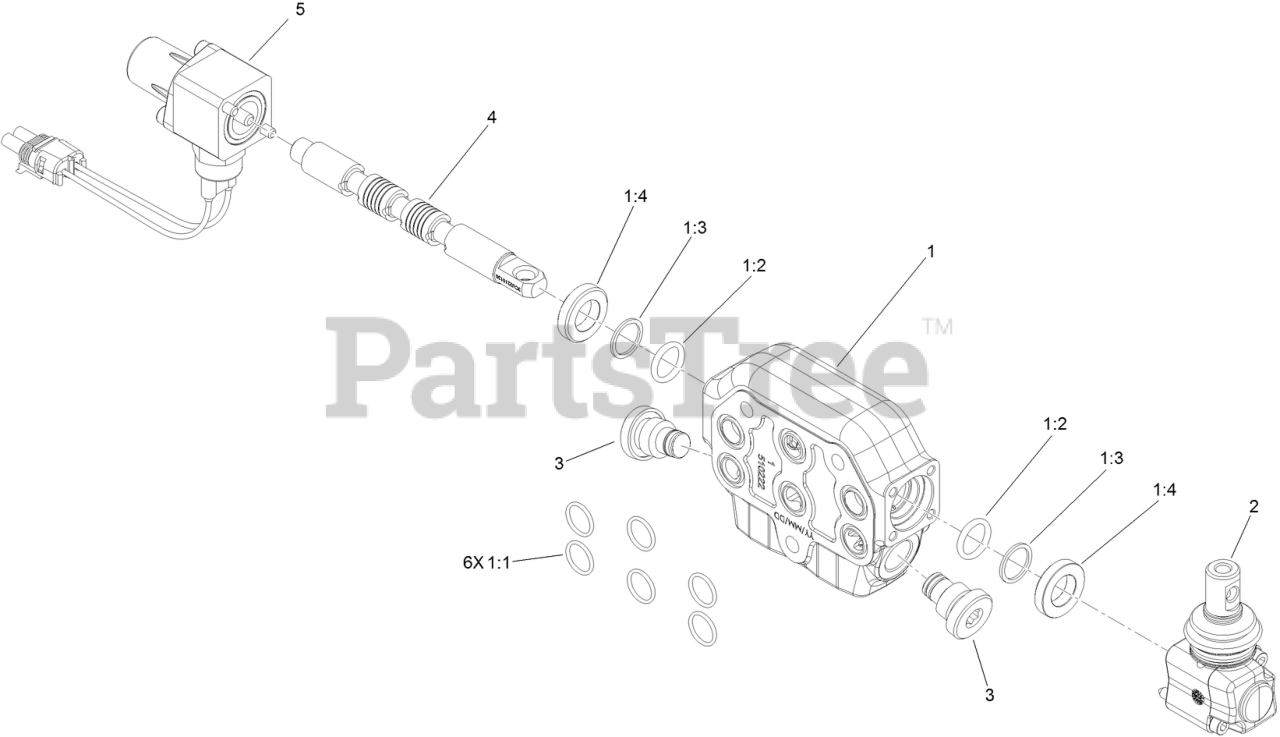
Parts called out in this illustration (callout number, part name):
1	SECTION-WORKING
1:1	O-RING
1:2	SEAL-VALVE
1:3	SEAL-VALVE
1:4	SEAL-VALVE
2	LEVER-VALVE
4	VALVE-SPOOL
5	KIT-CONTROL
